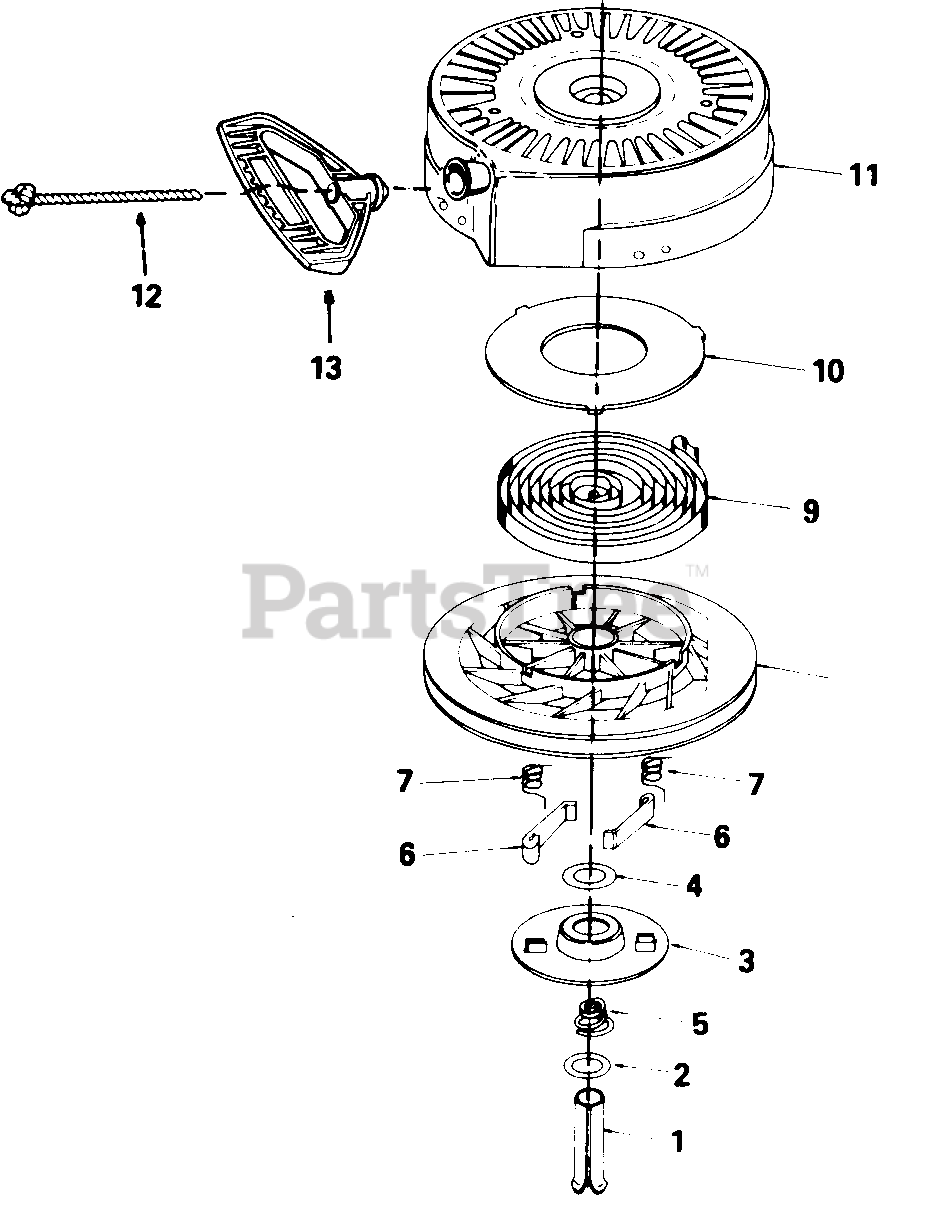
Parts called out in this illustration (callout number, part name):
1	Pin, Spring
5	Spring, Brake
6	Dog, Starter
7	Spring, Dog
9	Spring, Rewind
10	Cover, Spring
11	Housing Ass'y., Starter
12	Rope, Starter
13	Handle, Mitten Grip
